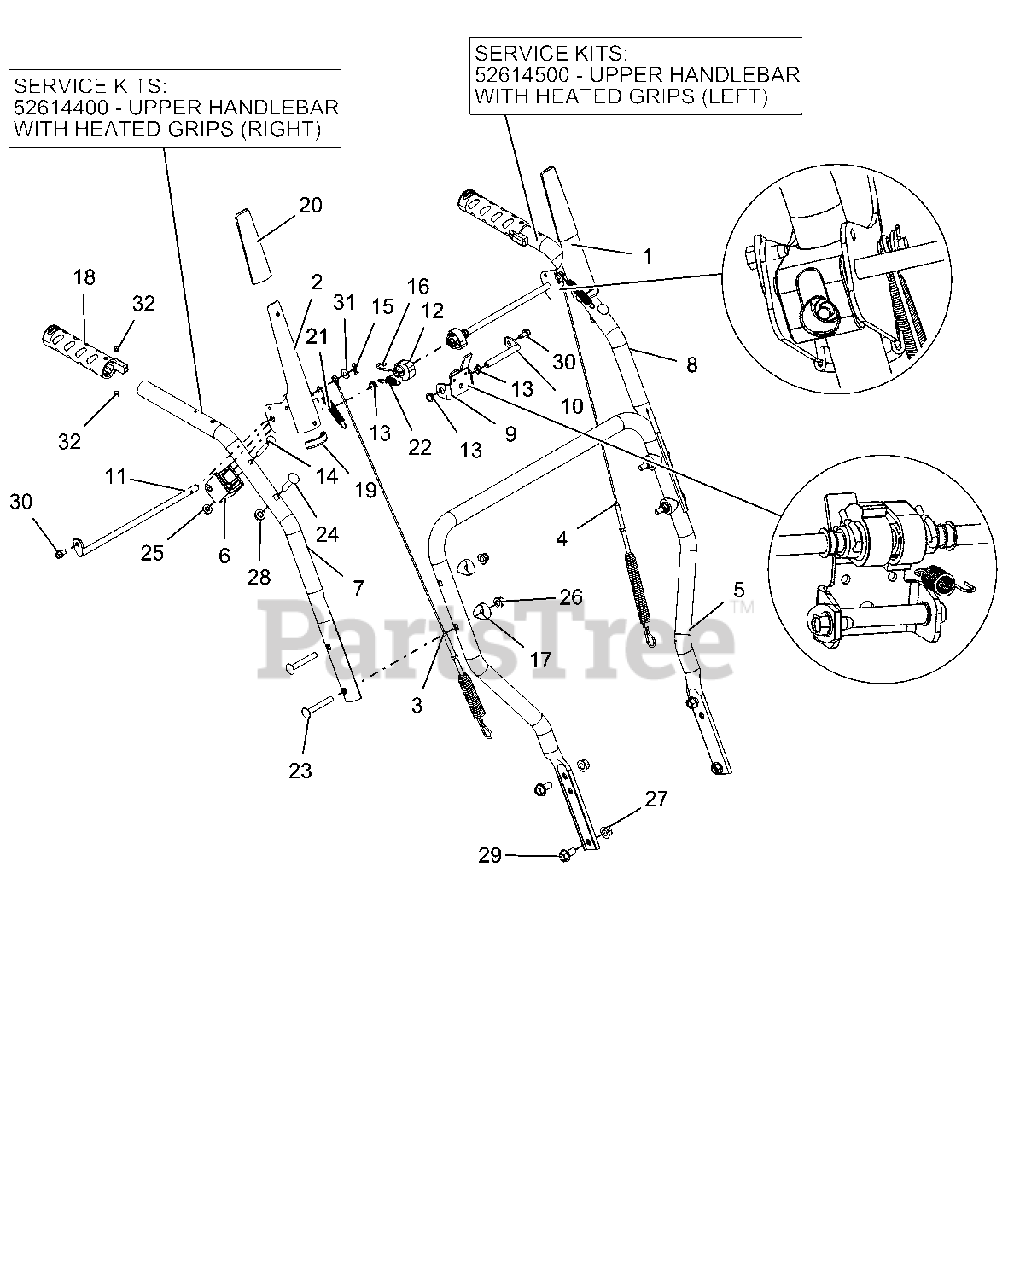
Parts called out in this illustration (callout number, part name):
1	LEVER, CLUTCH-LH
2	LEVER, CLUTCH-RH
3	CABLE, AUGER (DELUXE & PRO)
4	CABLE, UPPER TRACTION
5	HANDLEBAR, LOWER
6	BLOCK, CLUTCH PADDLE
7	HANDLEBAR, UPPER - RH
7	KIT, HANDLEBAR HW RH
8	HANDLEBAR, UPPER - LH
8	KIT, HANDLEBAR HW LH
9	BRACKET, INTERLOCK ARM
10	ROD, PIVOT - INTERLOCK
11	ROD, PADDLE MOUNT - PRO
12	CAM, INTERLOCK
13	BUSHING, POLYLINER-.38 SNAPIN
14	BLT-RDHDXLSQNK .25-20X2.0 G5YZ
15	PIN-HAIR INT .06X.18X.77
16	PIN, SPRING CLIP
17	SPACER, HANDLEBAR
18	GRIP,HEATED HANDLE-GRAY
19	EDGING, CLUTCH PADDLE - 2.00"
20	SLEEVE, CLUTCH PADDLE-GRAY
21	SPRING, EXTENSION
22	SPRING-EXT .047X.438X1.45
23	@BLT-RDHDSQNK .31-18X2.25 G5YZ
24	@BLT-RDHDSQNK .31-18X1.50 G5YZ
25	@NUT-LK-CTR-FLG .25-20 YWZC
26	@NUT-LK-NYL-FLG .31-18 YWZC
27	@NUT-LK-TOP-FLG .38-16 YWZC
28	@NUT-LK-TOP-FLG .31-18 YWZC
29	BLT-SERHFWH .38-16X.75 YWZC
30	SCR-TAP .25-20X.50 HWH TR YWZ
31	@WSHR-FL-STL.281X.62X.065 YWZC
32	RVT-POP #43 .125X.313 STL ZINC
